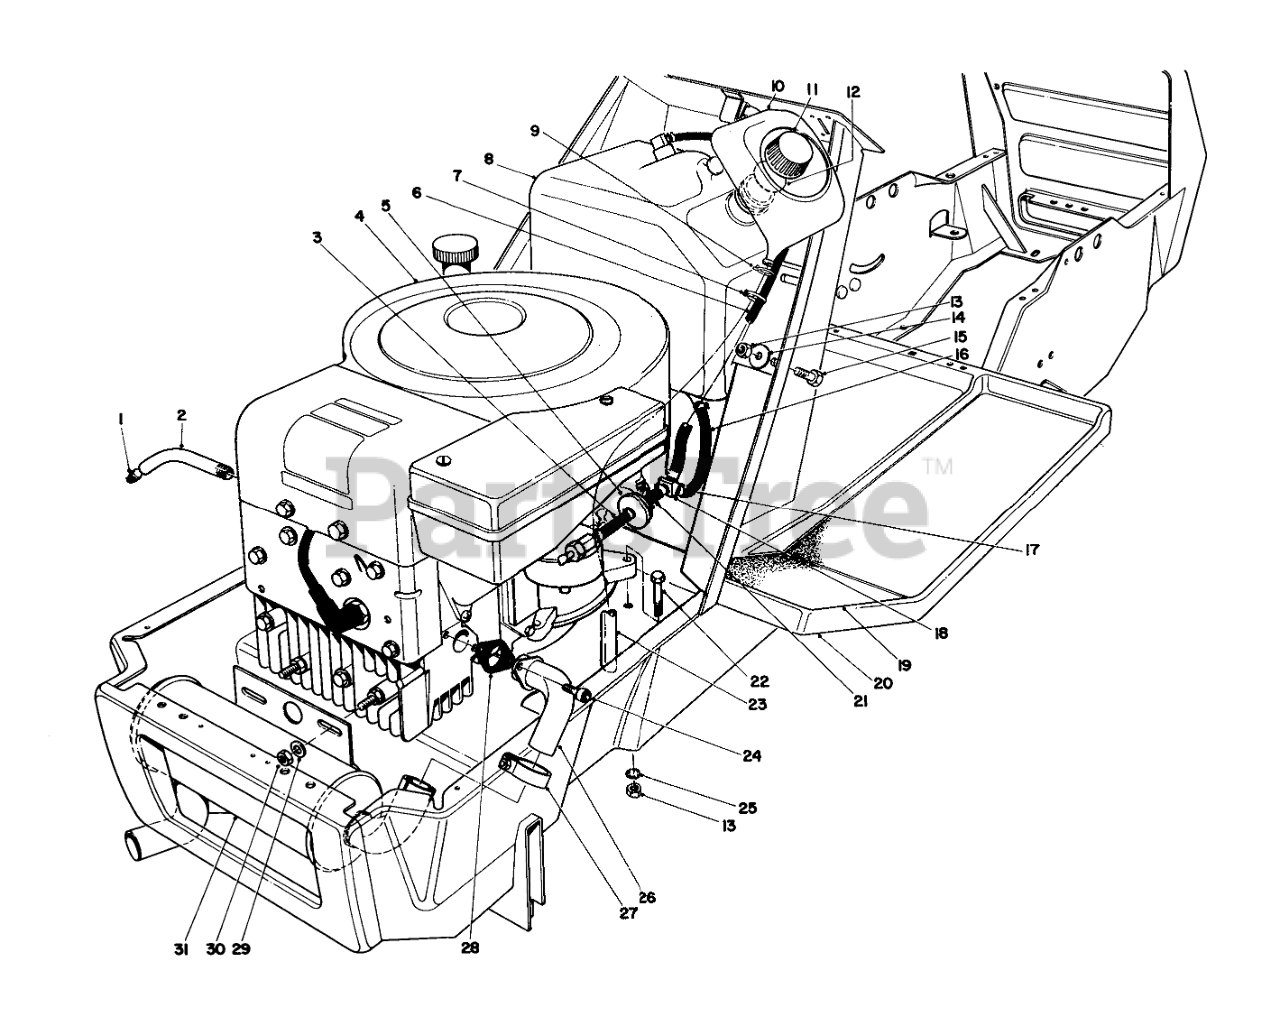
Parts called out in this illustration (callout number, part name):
1	PLUG-PIPE, SQH
2	OIL DRAIN TUBE
3	Hose Gas
4	Engine
5	Filter-Fuel
6	HOSE -RETURN
7	TIE-CABLE
8	Gas Tank Assy. (Incl. Ref. #9)
9	HOSE CLAMP
10	Funnel-Overflow
11	Gas Cap Assy. (Incl. Ref. #11)
12	GASKET
13	NUT-LOCK, NI
14	WASHER
15	SCREW-HH
16	HOSE-FUEL
17	CLAMP-HOSE
18	Fitting-Barbed Y
19	LH FOOT TREAD
20	Frame
21	GAS HOSE
22	SCREW-HH
23	FUNNEL HOSE
24	SCREW-HSH
25	WASHER-LOCK, INTERNAL
26	10 HP EXHAUST PIPE WA
27	MUFFLER CLAMP
28	Exhaust Gasket
29	WASHER-PLAIN
30	NUT-LOCK, CONE
31	EXHAUST MUFFLER 10 HP
